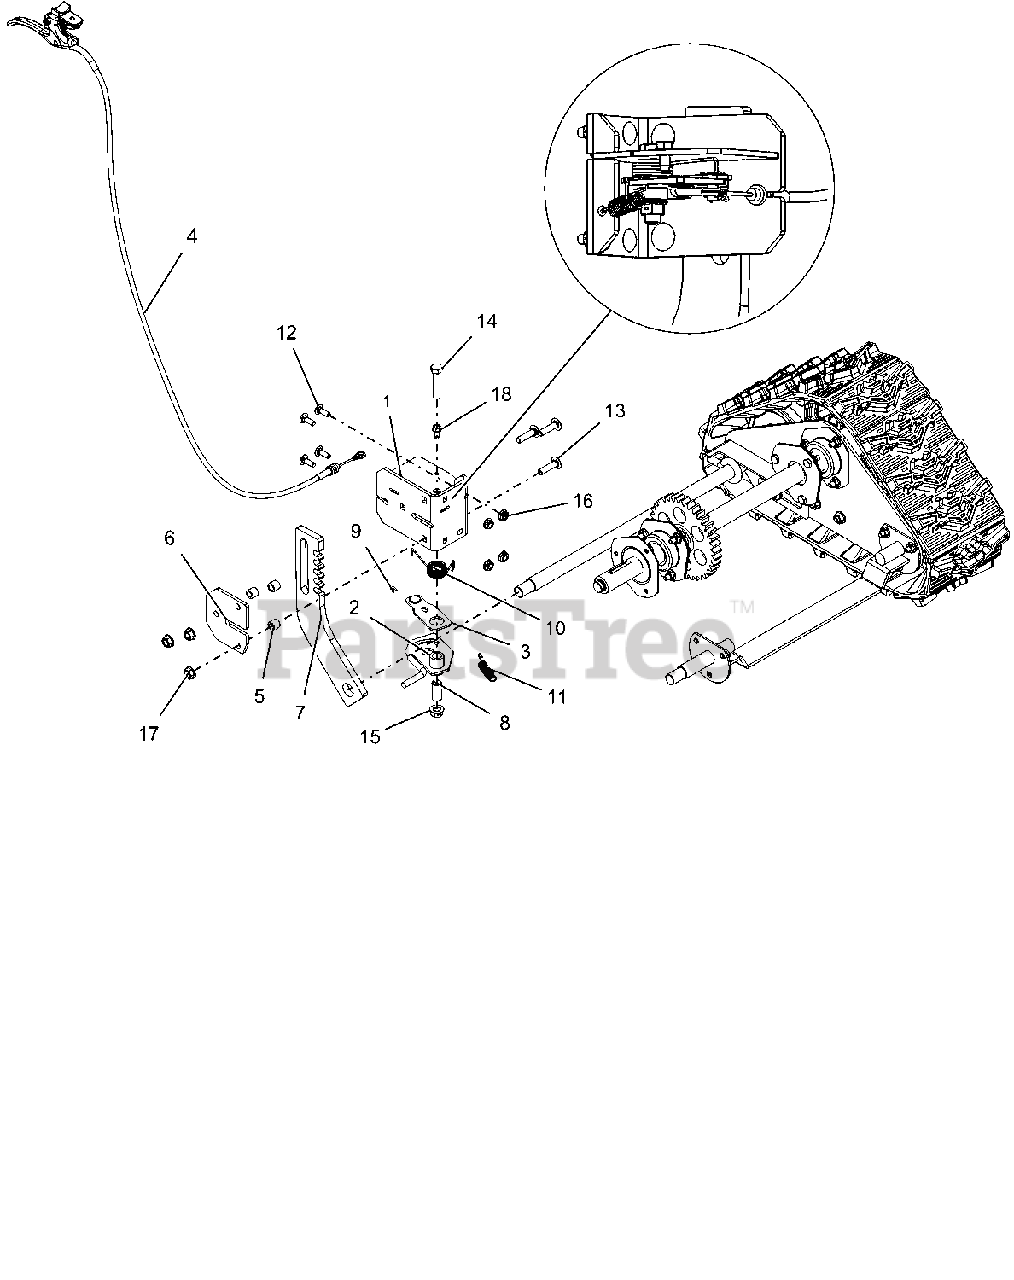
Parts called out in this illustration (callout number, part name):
1	BRACKET, HEIGHT ADJUSTER
2	LOCK, HEIGHT ADJUSTER
3	ARM, OVERTRAVEL
4	CABLE, TRACK REMOTE
5	SPACER .50 X .32 X .42
6	PLATE, HEIGHT ADJUSTER
7	STOP, HEIGHT ADJUSTER-CPT BLAC
8	BSHG-SLV .385X.500X1.045
9	PIN-HAIR INT .06X.18X.77
10	SG-TORS .067X.88
11	SPRING-EXT .047 X .438 X 1.85
12	@BLT-RDHDSQNK .25-20X.75 G5YZ
13	@BLT-RHDSHSQNK.31-18X1.25 G5YZ
14	@BLT-HEX .38-16X1.75 GR5 YWZC
15	NUT-LK-CTR-FLG .38-16 YWZC
16	@NUT-LK-CTR-FLG .25-20 YWZC
17	@NUT-LK-TOP-FLG .31-18 YWZC
18	SCR-TAP .25-20X.50 HWH TR YWZ
